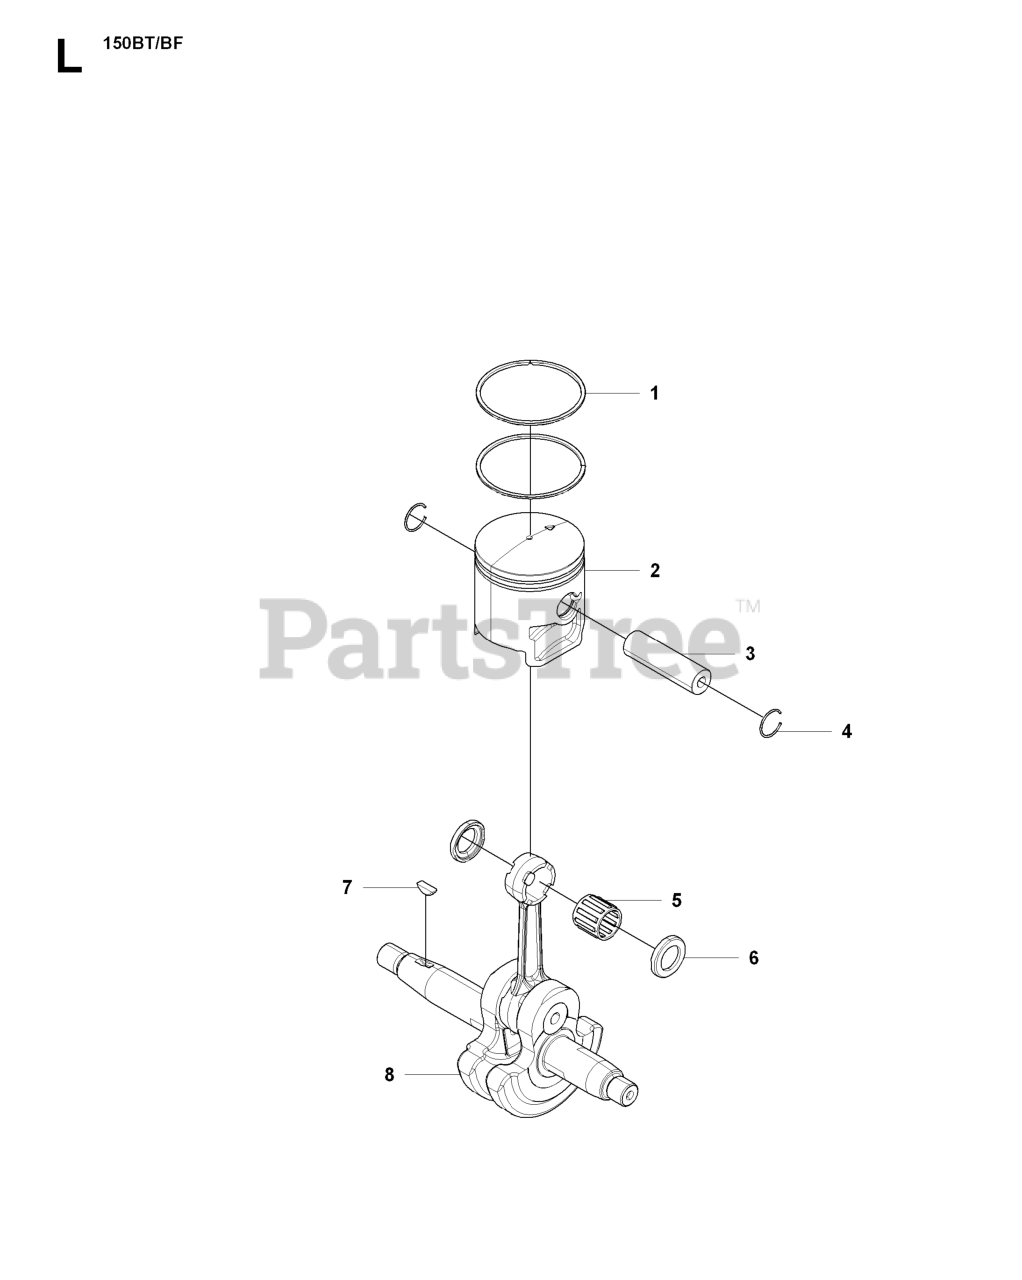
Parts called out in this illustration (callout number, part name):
1	PISTON RING
3	PISTON PIN
7	KEY
8	CRANKSHAFT
